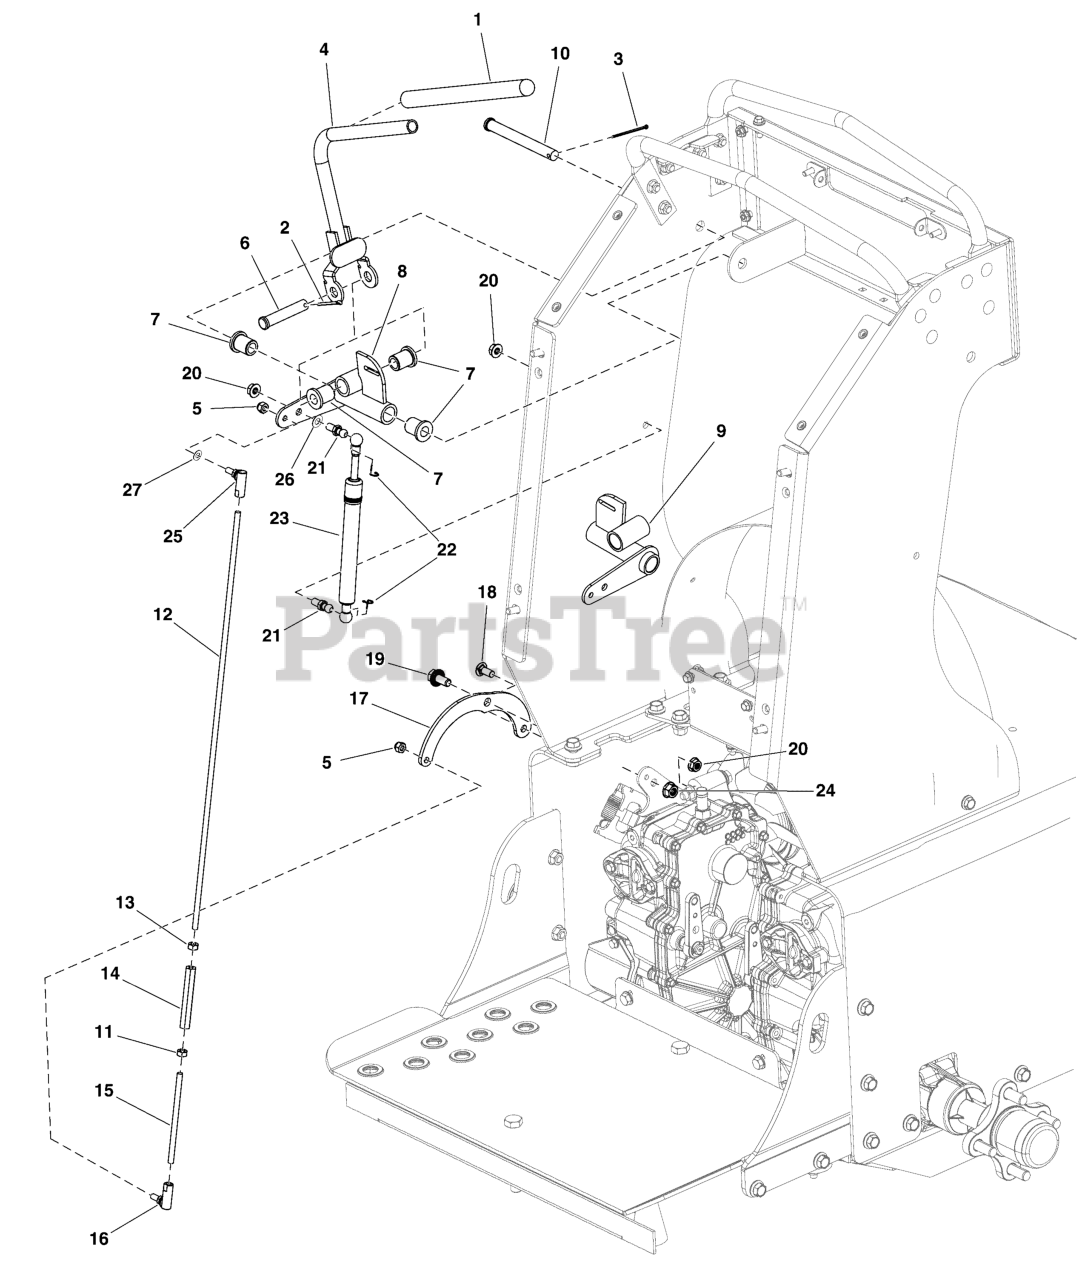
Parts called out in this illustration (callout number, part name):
2	PIN, COTTER, 1/8 X 1 1/2, CZ
3	PIN, COTTER
4	CONTROL, HANDLE
6	PIN, CLEVIS, 1/2 X 2-
8	BRACKET, Control
10	PIN, CLEVIS
11	NUT, 1/4
14	TUBE, CONNECTING
16	JOINT, BALL
17	ARM, CONTROL
18	BOLT, 5/16-18 X 3/4",
20	NUT, 5/16-18 HEX SERR
21	BALL STUD
23	DAMPENER
25	JOINT, BALL
26	WASHER
27	WASHER
